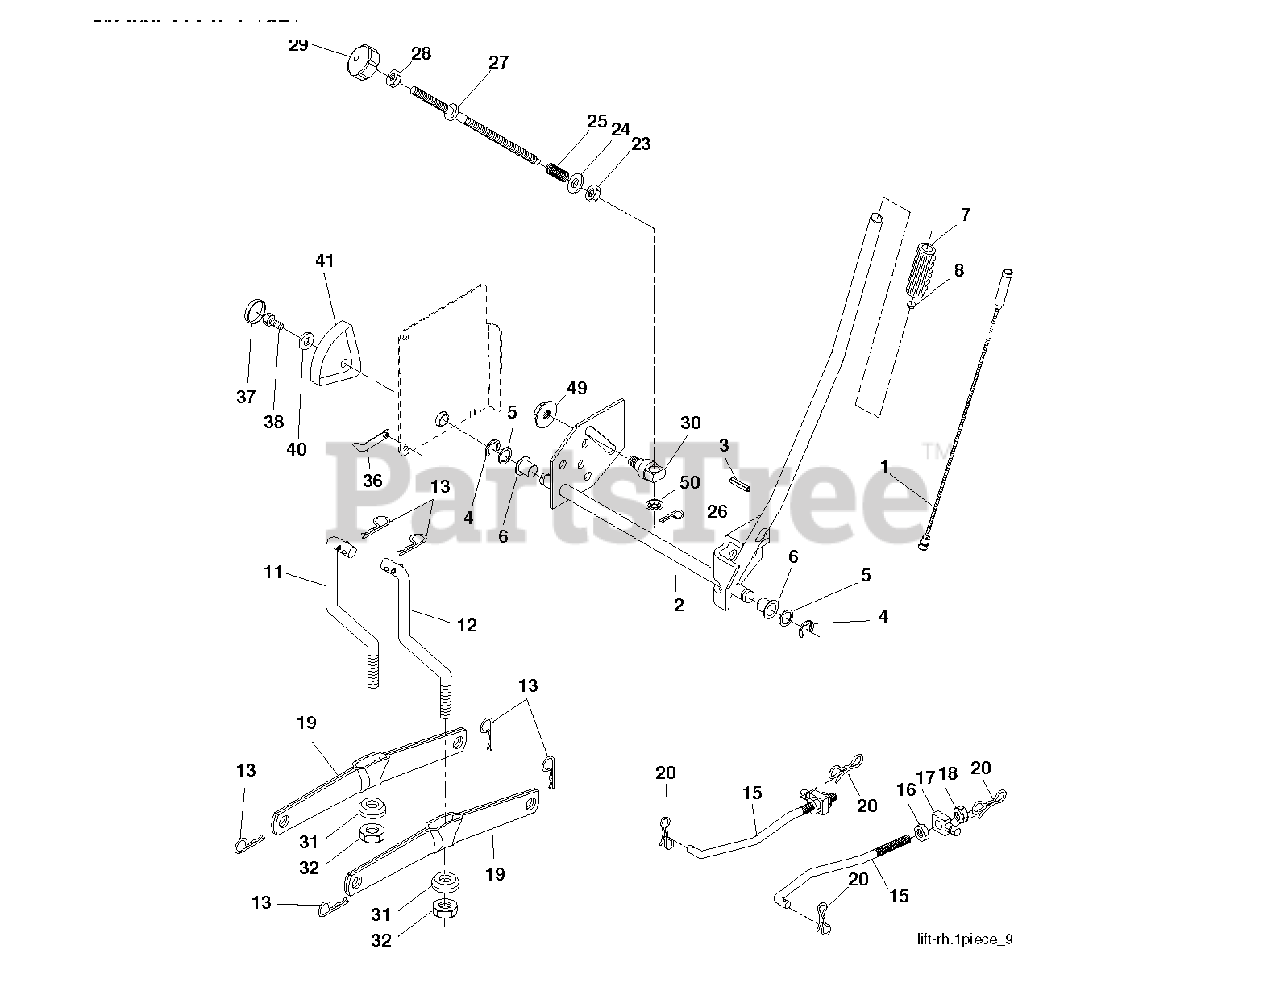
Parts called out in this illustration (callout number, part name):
1	PLUNGER.ASM.LIFT.LVR.BLK.17.32
2	SHAFT ASM R HANDLE
3	PIN GROOVE
4	RETAINING RING LT
6	BEARING.NYLON
7	GRIP HANDLE
8	PLUNGER BUT KIT
11	LINK
12	LINK
13	RETAINER-SPRNG RB
15	LINK.SUSPENSION.FRONT
16	NUT
18	NUT
19	ARM.REAR.SUSPENSION
20	PIN.COTTER.7/16.BOW TI
25	SPRING**
26	RETAINER CLIP
27	ROD ADJ LIFT
28	NUT
29	KNOB INF 3/8-16
31	BEARING.PIVOT.LIFT
32	NUT CROWNLOCK 3/8-24
36	POINTER, HEIGHT INDICATOR
37	PLUG,HOLE
38	SCREW 5/16-18X1
41	HEIGHT INDICATOR
49	NUT
50	NUT PUSH M
